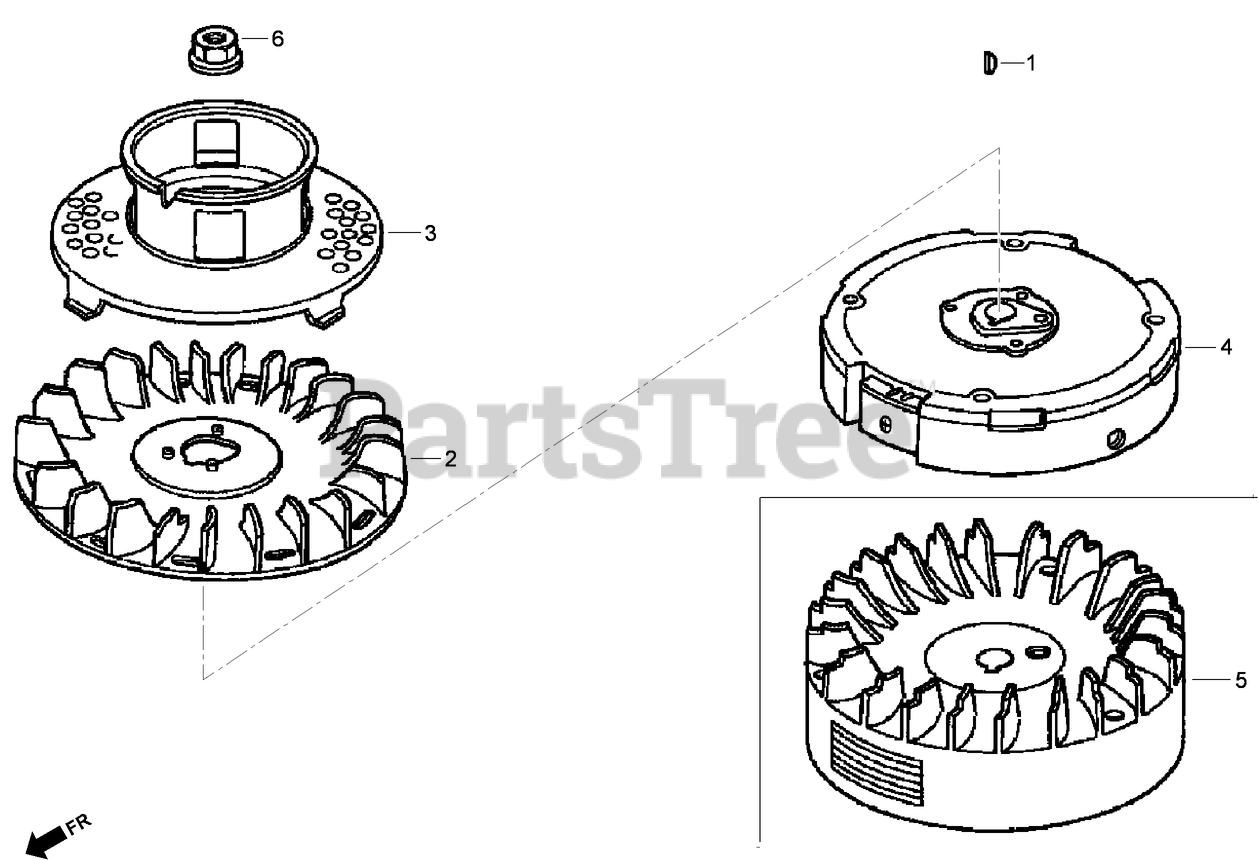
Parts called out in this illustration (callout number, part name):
1	KEY-WOODRUFF, SPECIAL (25X18)
2	FAN-COOLING (Engine Serial No. From 1036456)
3	PULLEY-STARTER
4	FLYWHEEL (Engine Serial No. From 1036456)
5	FLYWHEEL (BRAKE)
6	NUT-SPECIAL (14 mm)
